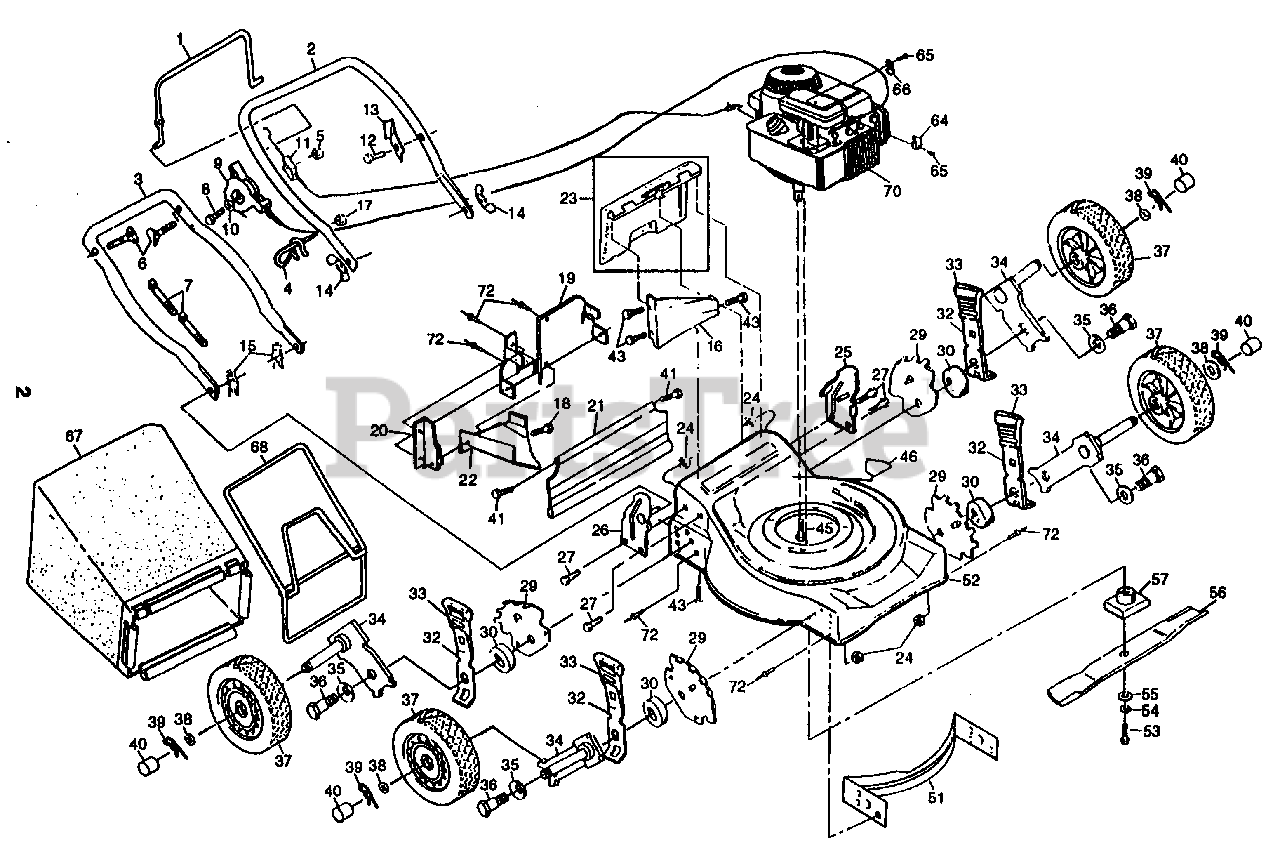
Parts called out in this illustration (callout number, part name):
1	Control Bar (AYP part number)
2	Upper Handle (AYP part number)
3	Lower Handle (AYP part number)
4	Rope Guide
5	Locknut 1/4-20 (AYP part number)
6	Handle Bolt (AYP part number)
7	Wire Tie (AYP part number)
8	Machine Screw 1/4-20 x 2 1/8 (AYP part number)
9	Throttle Control
10	Washer (AYP part number)
11	Engine Zone Control Cable
12	Hex Washer Head Screw #10-24 x 1/2 (AYP part number)
13	Up-Stop Bracket (AYP part number)
14	Wing Nut (AYP part number)
15	Hairpin Cotter (AYP part number)
16	Rear Baffle (AYP part number)
17	Keps Locknut 1/4-20 (AYP part number)
18	Self Tapping Screw #10-24 x 1/2 (AYP part number)
19	Back Plate (AYP part number)
20	Side Baffle (AYP part number)
21	Rear Skirt (AYP part number)
22	Discharge Baffle (AYP part number)
23	Rear Door Assembly Kit (AYP part number)
24	Locknut 3/8-16 (AYP part number)
25	Handle Bracket Assembly (Left) (AYP part number)
26	Handle Bracket Assembly (Right) (AYP part number)
27	Screw 5/16-18 x 3/4 (AYP part number)
29	Wheel Adjusting Bracket (AYP part number)
30	Spacer (AYP part number)
32	Selector Spring (AYP part number)
33	Selector Knob Deluxe (AYP part number)
34	Axle Arm Assembly (AYP part number)
35	Belleville Washer (AYP part number)
36	Shoulder Bolt 3/8-16 (AYP part number)
37	Wheel Assembly (AYP part number)
38	Washer (AYP part number)
39	Retainer Clip (AYP part number)
40	Hubcap (AYP part number)
41	Hinge Screw (AYP part number)
43	Hex Tapping Screw 1/4-20 x 1/2 (AYP part number)
45	Hex Head Thread Rolling Screw 3/8-16x1 (AYP part number)
46	Danger Decal (AYP part number)
51	Front Baffle (AYP part number)
52	Housing Assembly
53	Hex Head Screw 3/8-24 x 1-3/8 Grd. 8
54	Helical Lock Washer (AYP part number)
55	Hardened Washer (AYP part number)
56	20" Blade
57	Blade Adapter (AYP part number)
64	Cable Clamp (AYP part number)
65	Screw #10 x 5/8 (AYP part number)
66	Guide Clip (AYP part number)
67	Grass Bag (AYP part number)
68	Catcher Frame
72	Pop Rivet (AYP part number)
